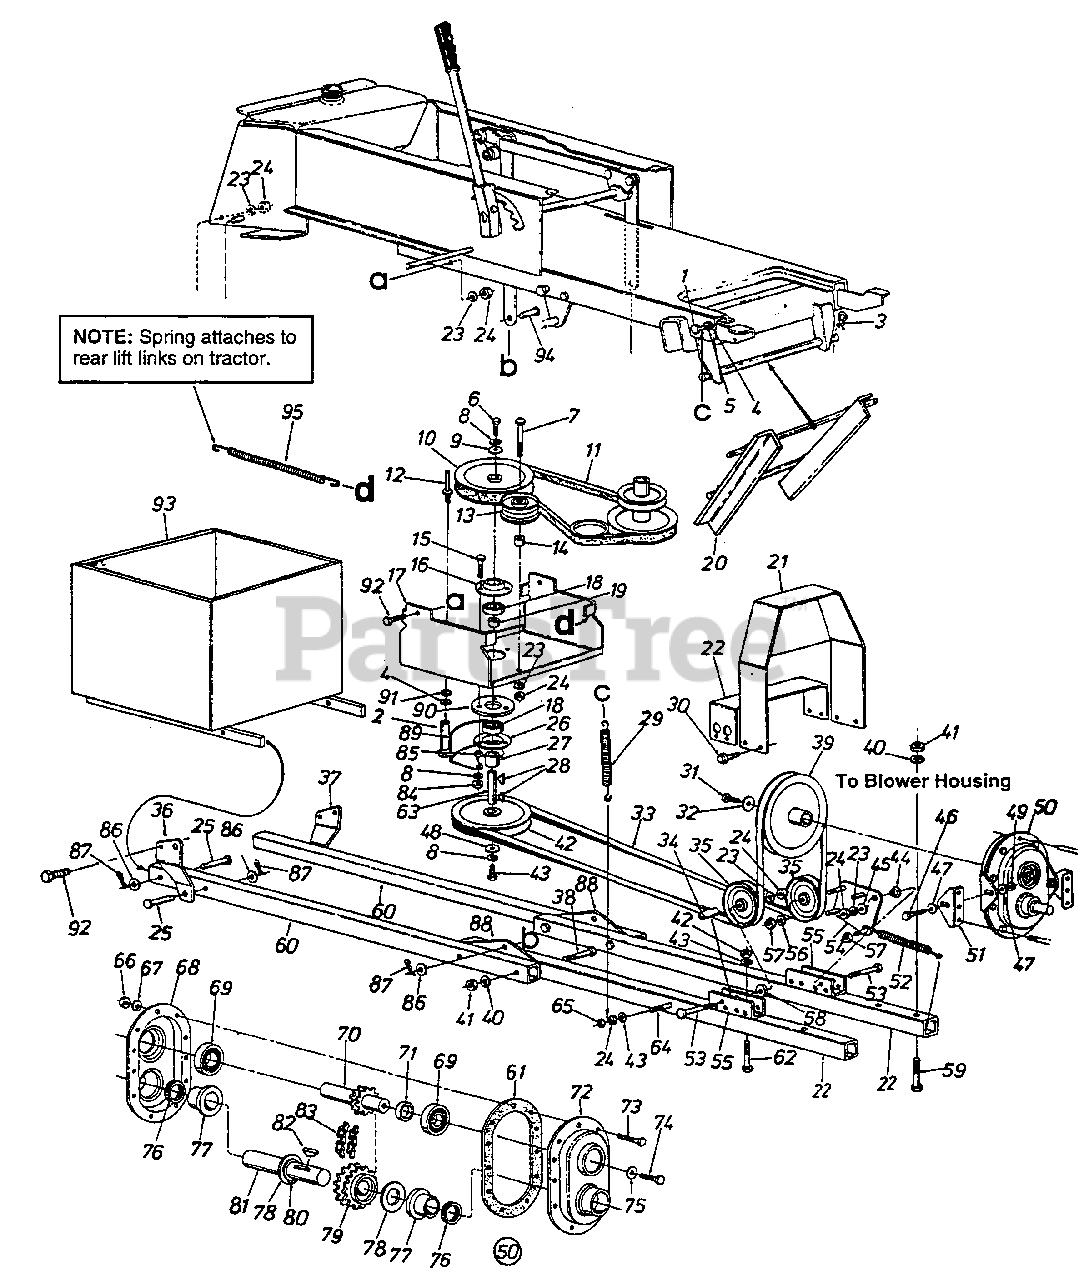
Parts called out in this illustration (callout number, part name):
1	Hex Bolt 5/16-24 x 2" Lg.
2	Clevis Pin Spec. 3/8" Dia. x 2.62" Lg.
3	Intern. Cot. Pin
4	L-Wash. 1/4" I.D.
5	Hex Nut 1/4-28 Thd.
6	Hex L-Scr. 3/8-24 x 1.0" Lg.
7	Hex Bolt 3/8-16 x 2.25" Lg.
8	L-Wash. 3/8" I.D.
9	Fl-Wash.
10	5/8" "V"-Pulley .79" I.D. x .65" O.D.
11	"V"-Belt
12	Belt Guard Pin
13	Fl-Idler 3.75" O.D.
14	Spacer .385" I.D. x .63" O.D. x .76"
15	Hex Bolt 5/16-24 x 1.50
16	Open Brg. Hsg.
19	Spacer .8" I.D. x 1" O.D.
20	Guide Brkt. Ass'y.
21	Belt Cover Ass'y.
24	Hex Nut 3/8-16 Thd.
25	Clevis Pin .50" Dia. x 1.75" Lg.
26	Brg. Hsg. Ass'y.
27	Spacer .8" I.D. x 1" O.D. x .125"
28	Woodruff Key 3/16" x 5/8" NT
29	Helper Spring
30	Hex Wash. HD-Tap Scr. 5/16-18 x .50
31	Hex L-Scr. 3/8-24 x 1.0" Lg.
33	"V"-Belt
34	Spacer .39" I.D. x .62" O.D. x 1.74" Lg.
35	V-idler Pulley
39	5/8" "V"-Pulley 7.5" O.D.
40	L-Wash. 1/2" I.D.
41	Hex Nut 1/2-13 Thd,
42	5/8" "V"-Pulley
44	Shld. Spacer
45	Fl-Wash. .4" I.D. x 1.25" O.D. x .16"
46	Hex Bolt 5/16-18 x 1.25" Lg.
47	Bell-Wash. .345" I.D. x .88" O.D. x .06"
49	Hex Nut 5/16-18 Thd.
50	Comp. Chain Gear Box Ass'y.
51	Gear Box Support Brkt.
52	Ext. Spring .6" Lg.
56	L-Wash. 5/16" I.D.
57	Hex Nut 3/8-24 Thd.
59	Hex Bolt 1/2-13 x 3" Lg.
60	Sq. Tubing 43" Lg.
61	Gasket
62	Hex Bolt 3/8-16 x 3" Lg.
63	Shaft - .787" Dia. x 3.81" Lg.
65	Hex L-Nut 3/8-16 Thd.
67	Wave Spring Wash. .27" I.D. x .51" O.D. x .03"
68	Complete Gear Hsg. Half - L.H.
69	Ball Brg. 1" I.D. x 2" O.D.
70	11-2 x .5 Pitch Sprocket Shaft Ass'y.
71	Spacer 1" I.D. x 1.18" O.D. x .44"
72	Comp. Gear Hsg. Half - R.H.
73	Hex Bolt 1/4-28 x 1" Lg.
74	Hex L-Scr. 3/8-24 x 1" Lg.
76	Oil Seal 1.25" I.D.
77	Flange Brg. 1.25" I.D.
78	Fl-Wash. 1.25" I.D. x 2" O.D. x .036"
79	DBL Sprocket 19-2 Teeth x .5" Pitch
80	Snap Ring for 1.25" Dia. Shaft
81	Gear Shaft 1.25 Dia. x 6" Lg.
82	Hi-Pro Key 1/4" x 7/8"
83	40-2 Chain 1/2" Pitch x 25 Links
84	Hex Nut 5/16-24 Thd.
85	Spacer .380" I.D. x .625" O.D. x .227
86	Fl-Wash. .53" I.D. x 1" O.D. x .06"
88	Attaching Plate
91	Hex L-Nut 1/4-20 Thd.
92	Hex Bolt 3/16 x 1 Lg.
93	Weight Box Ass'y.
95	Extension Spring
